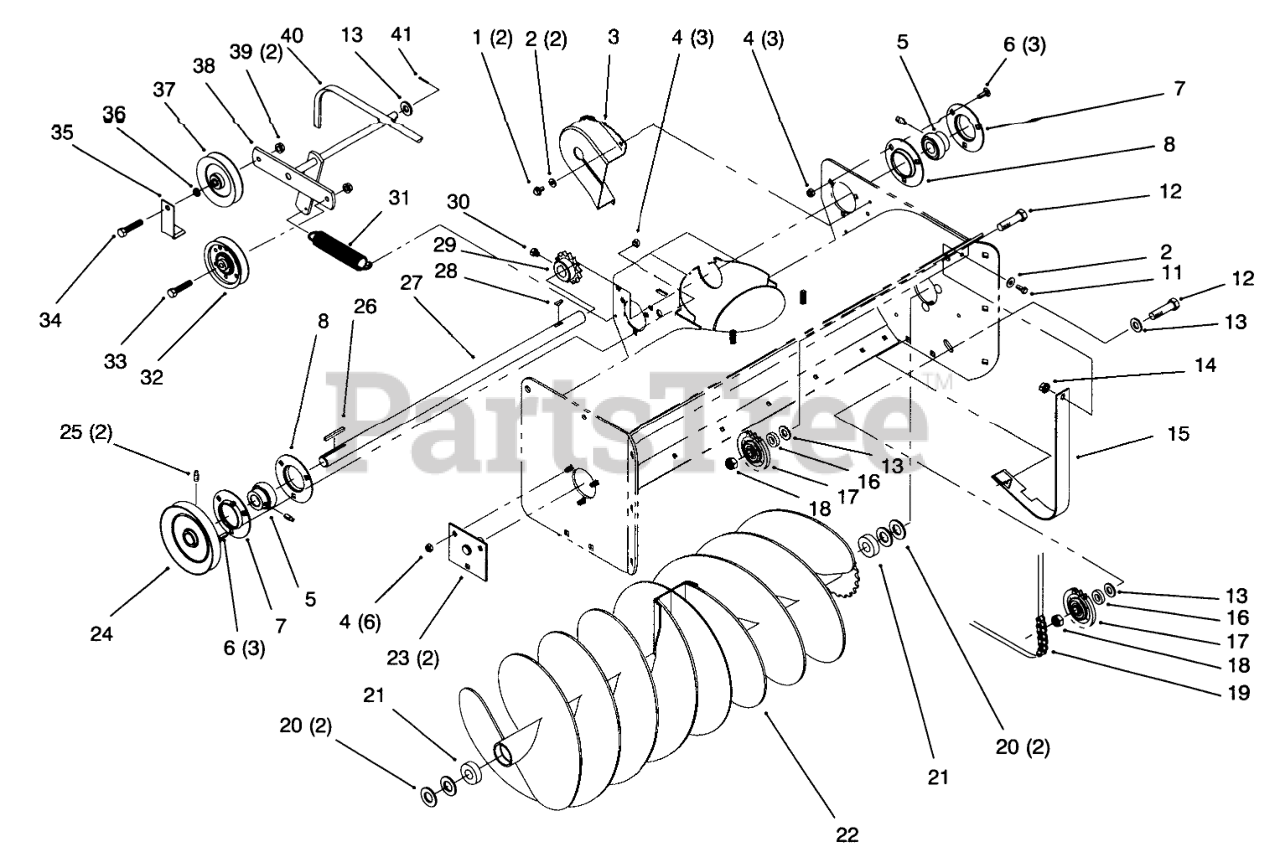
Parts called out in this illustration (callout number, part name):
1	SCREW-HWH
2	WASHER-FLAT
3	GUARD-CHAIN
4	NUT-LOCK, NI
5	BEARING AND COLLAR
6	BOLT-CARR
7	FLANGE-ZERK RELUBE
8	Flange
11	SCREW-HH
12	SCREW-HH
13	WASHER-FLAT
14	NUT-KEPS
15	Guard
16	SPACER
17	Idler Sprocket
18	NUT-LOCK, NI
19	CHAIN
20	WASHER-FLAT
21	BEARING-BALL
22	Auger
23	SUPPORT
24	PULLEY
25	SCREW-SQH
26	KEY-STRAIGHT
27	Shaft
28	KEY-WOODRUFF
29	SPROCKET-14T H.T.
30	SCREW-SET, HSH
31	SPRING-EXTENSION
32	PULLEY-IDLER, FLAT
33	SCREW-HH
34	SCREW-HH
35	Spacer
36	SPACER
37	PULLEY-IDLER
38	Arm Idler
39	NUT-LOCK, NI
40	V-BELT
41	PIN-COTTER
